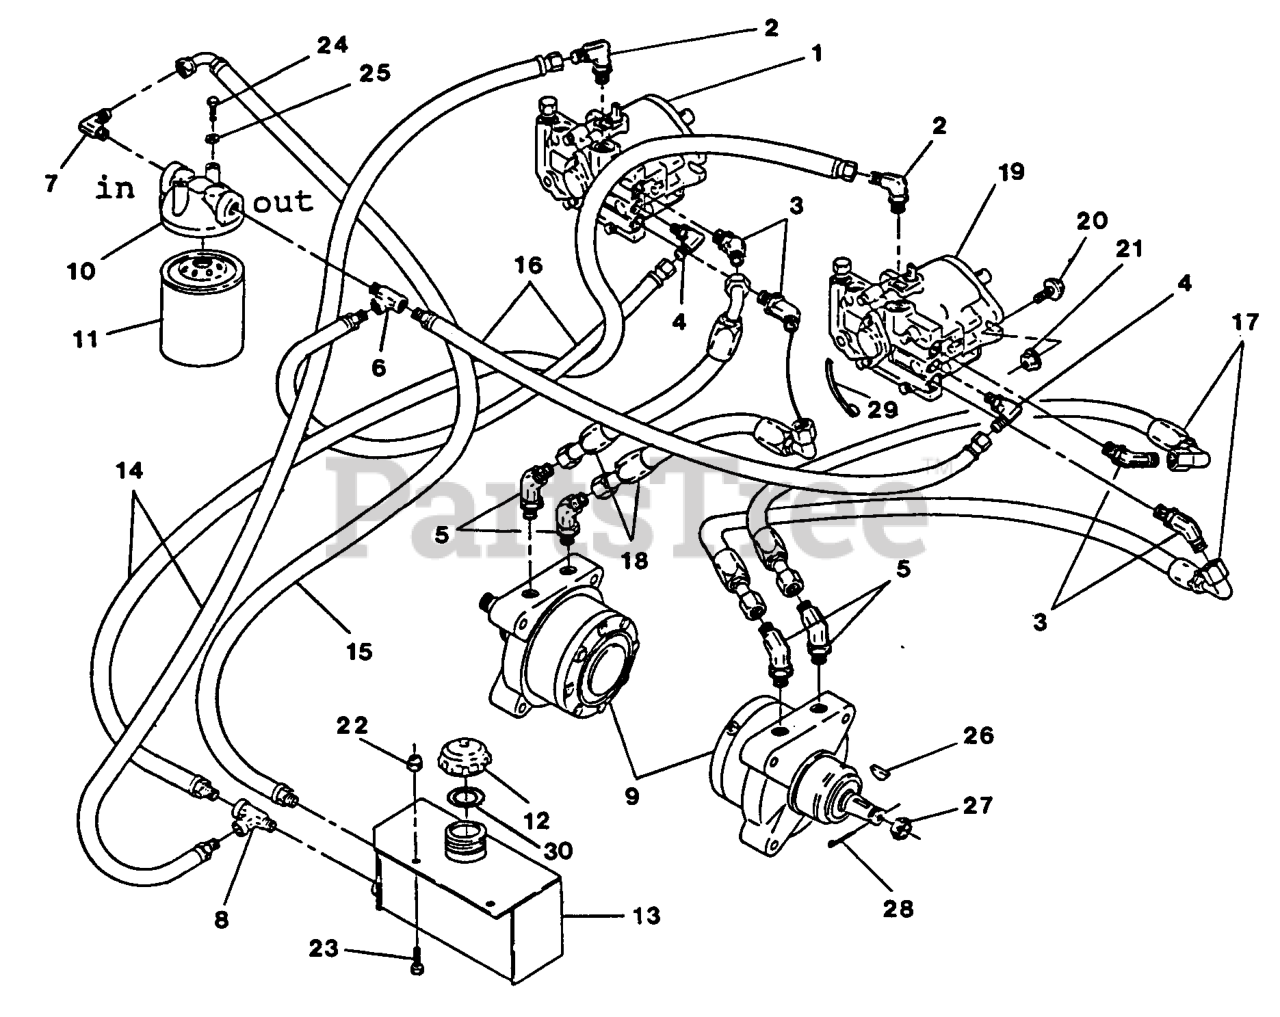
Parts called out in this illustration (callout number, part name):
2	FITTING-90 DEG
4	ELBOW,90 DEGREE
5	FITTING,45 DEGREE
10	FILTER-HEAD
25	WASHER-LOCK
28	PIN-COTTER
29	TIE-PLASTIC
30	GASKET-CAP, TANK
